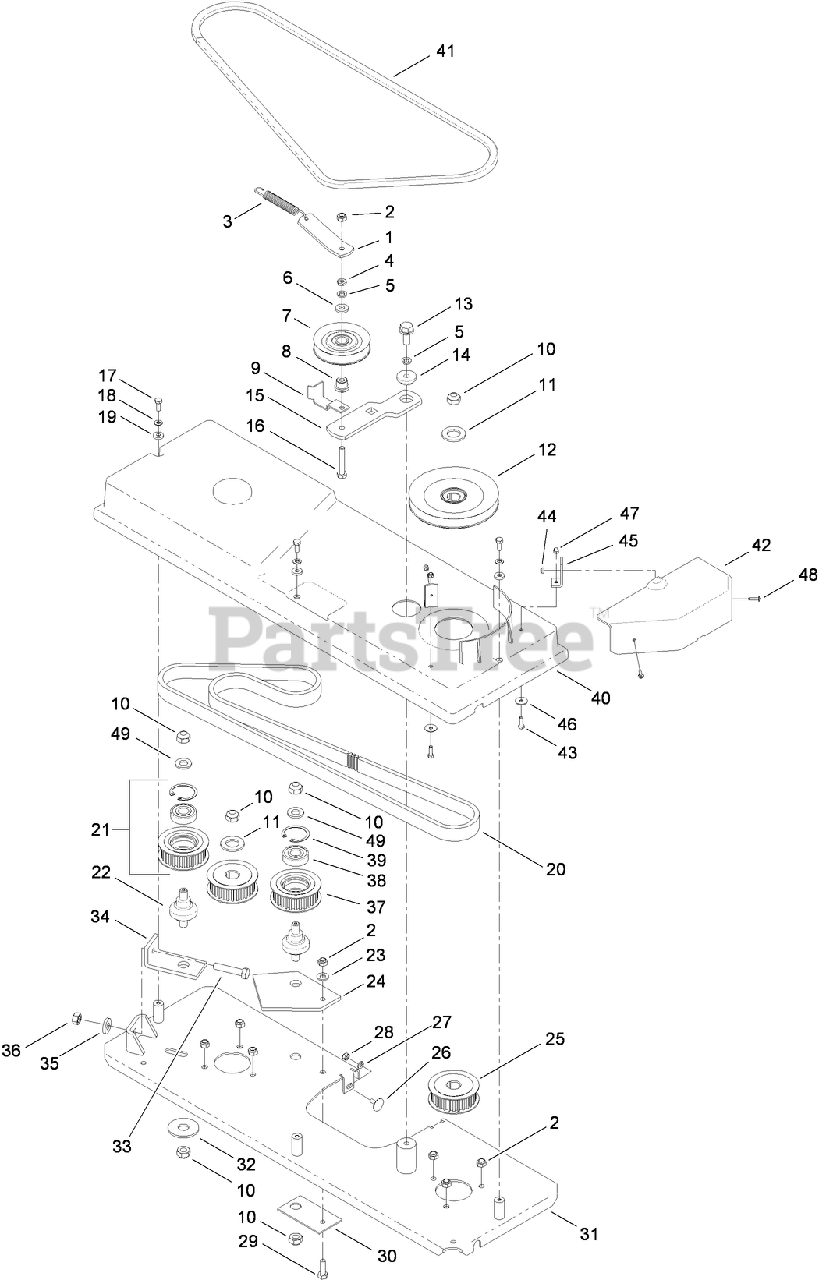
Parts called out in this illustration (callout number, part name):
1	LEVER-ENGAGEMENT
2	NUT
3	SPRING
4	NUT-JAM
5	WASHER-LOCK
6	Washer-Flat
7	PULLEY-IDLER
8	BUSHING
9	RETAINER-BELT
10	NUT-LOCK, HEX NI
11	WASHER-FLAT
12	PULLEY-DRIVE
13	SCREW-HHF
14	SHIM-ARM, IDLER
15	ARM-IDLER
16	SCREW-HH
17	SCREW-HH
18	Washer-Flat
19	WASHER-RUBBER
20	Belt-Cog
21	COG PULLEY ASM
22	PIN-PULLEY, Cog
23	WASHER-PLAIN
24	SUPPORT-PULLEY
25	PULLEY-COG, DRIVE
26	SCREW-CARR
27	WASHER-FLAT
28	NUT-LOCK
29	SCREW-HH
30	PLATE-ANCHOR
31	PLATE-DRIVE, BLADE
32	WASHER
33	SCREW-HH
34	BRACKET-IDLER
35	WASHER-FLAT
39	RING-LOCKING
40	Belt-Cover
41	V-BELT
42	GUARD-BELT
43	SCREW-HH
44	NUT-LOCK
45	BRACKET
46	WASHER-FLAT
47	NUT-LOCK
49	WASHER-FLAT
